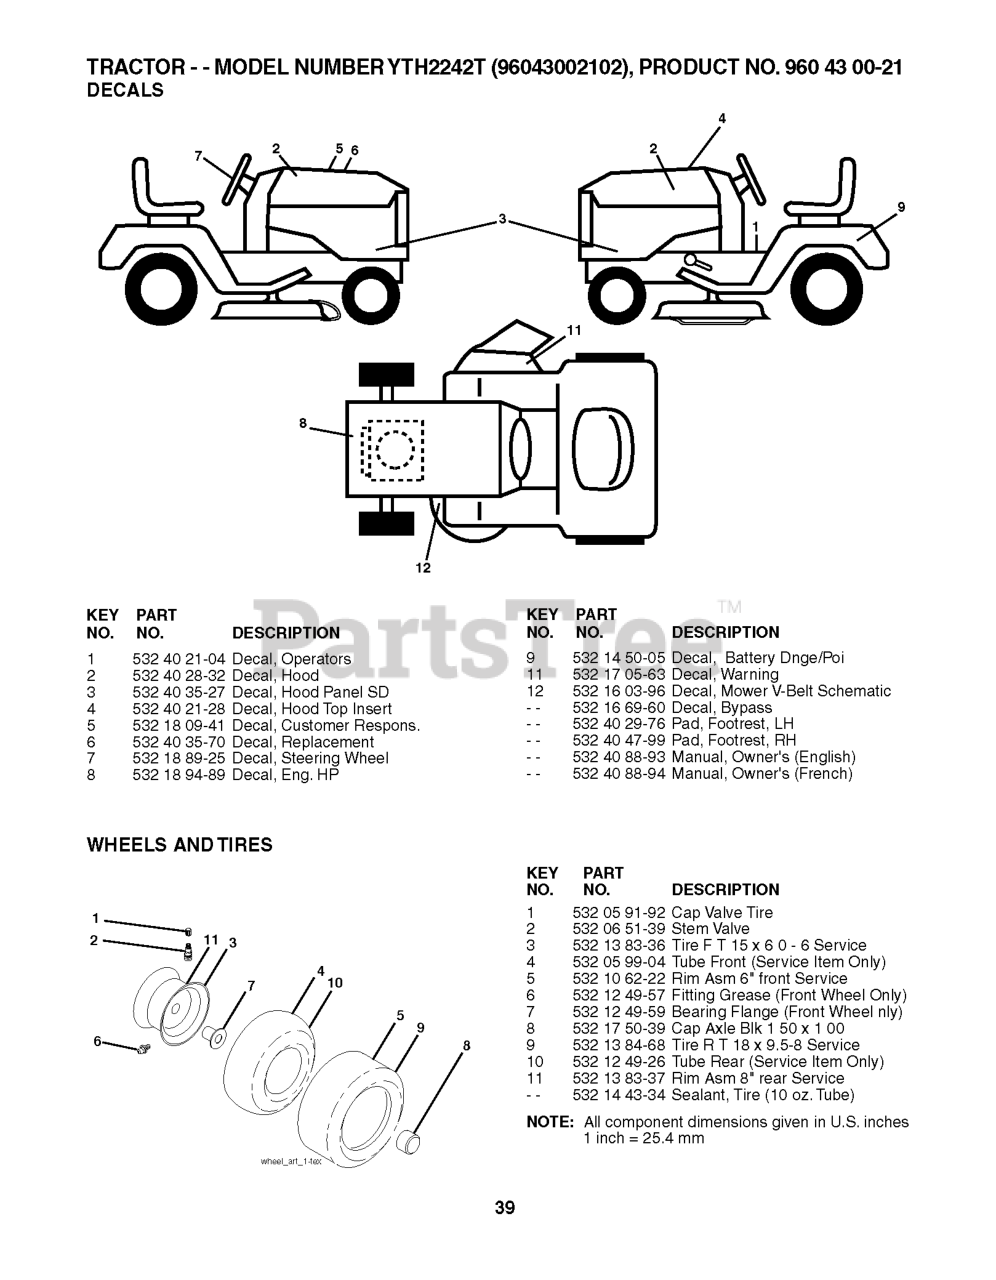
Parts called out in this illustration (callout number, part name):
1	DECAL.FENDER.OPER.TEX.
2	DECAL.HOOD.NAMELOGO.HUSQ
3	DECAL.PANEL.SD.YTH2242
4	DECAL.HOOD.TOP.INSERT.
5	DECAL HOOD CUST. RESP.
6	DECAL.RPL.B&S.22
7	DECAL.STEERING.HUSQ.BLUE
8	DECAL.B&S.22HP#275796
9	DECAL BTRY SYMBOLS
11	DECAL.WARN.KEEP.HAND.AWAY
12	DECAL V BELT SCHEMATIC
